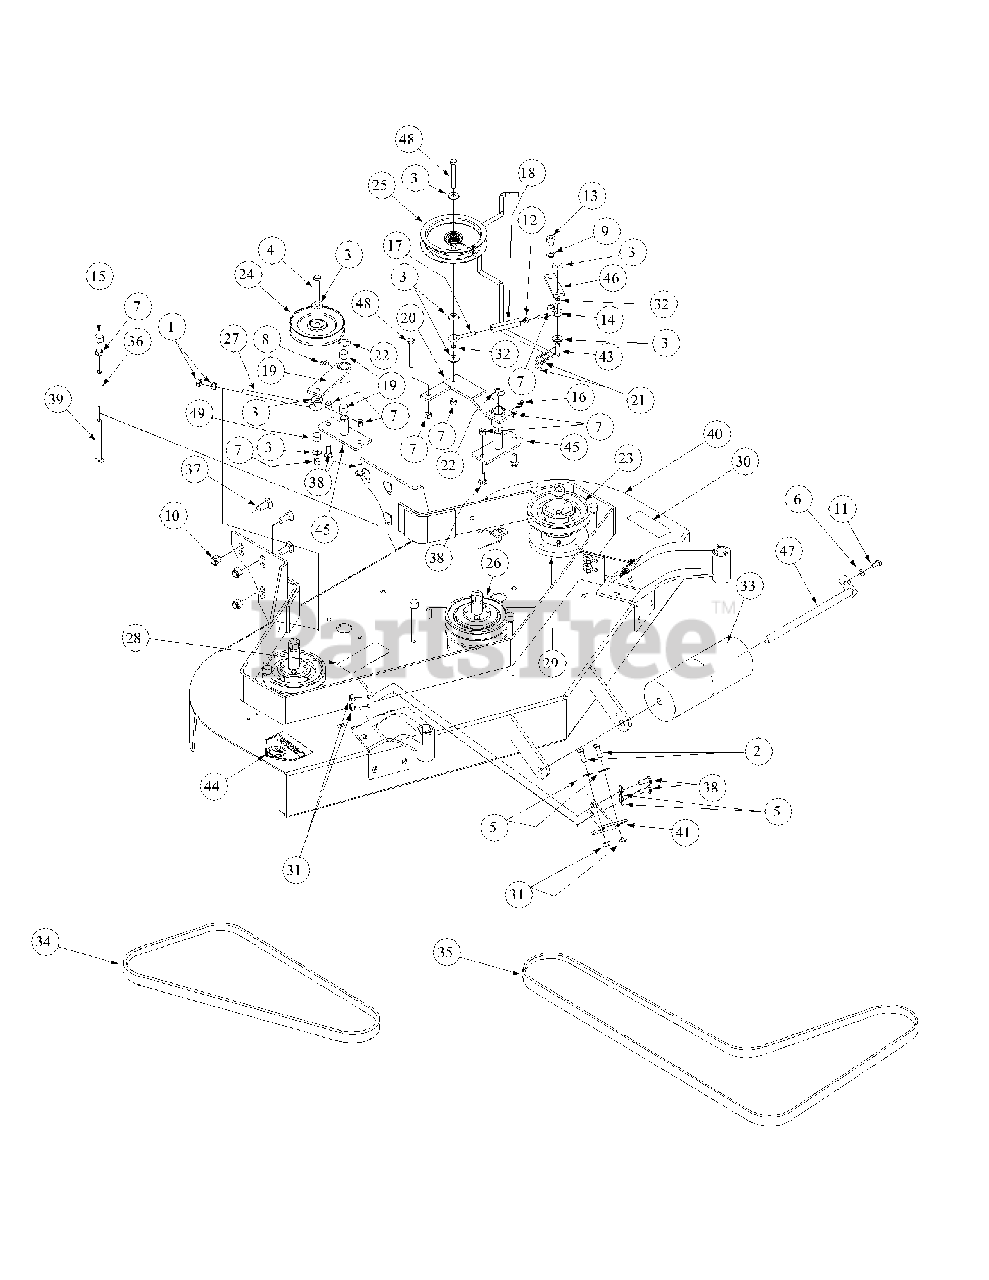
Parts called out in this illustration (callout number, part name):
1	Hex Nut, 3/8-16
2	Hex Cap Screw, 3/8-16, 1
3	Flat Washer, 3/8 Zinc
4	Hex Cap Screw, 3/8-16, 1
5	Flat Washer, 3/8 Zinc
6	Flat Washer, 5/16 Zinc
7	Lock Nut, Nylon Insert, 3/8-16
8	Grease Fitting, 1/4-28, 90°.
9	Shim Washer
10	Lock Nut, Nylon Insert, 1/2-13
11	Hex Cap Screw, 5/16-18 x 3/4
12	Hex Nut, 5/16-18
13	Shoulder Bolt
14	Eye Bolt, Right Hand
15	Vinyl Cap
16	Grease Fitting, 1/4-28, 45°.
17	Eye Bolt, Left Hand
18	Turnbuckle
19	Idler Arm "B"
20	Idler Arm "A"
21	Hair Pin, 3/8-1/2
23	Deck Pulley
24	Idler Pulley
25	Idler Deck Take-up
26	Double Pulley
27	Rod Belt Tensioner
28	Decal Rotating Blade
29	Spindle Backing Plate
30	Decal Warning Shield Missing
31	Lock Nut, Metal, 3/8-16
32	Sleve Turnbuckle
34	Drive Belt
35	Drive Belt
36	Spacer Belt Guide
37	Carriage Bolt, 1/2-13 x 1-1/4
38	Carriage Bolt, 3/8-16 x 2
39	Carriage Bolt, 3/8-16 x 4-1/2
40	Mower Deck Weldment, 52"
41	Caster Support Assembly
43	Rod Clutch Link
44	Decal, Danger Hands and Feet
45	Idler Base
47	Axle
48	Hex Cap Screw, 3/8-16, 2.75
49	Sleeve Tensioner
